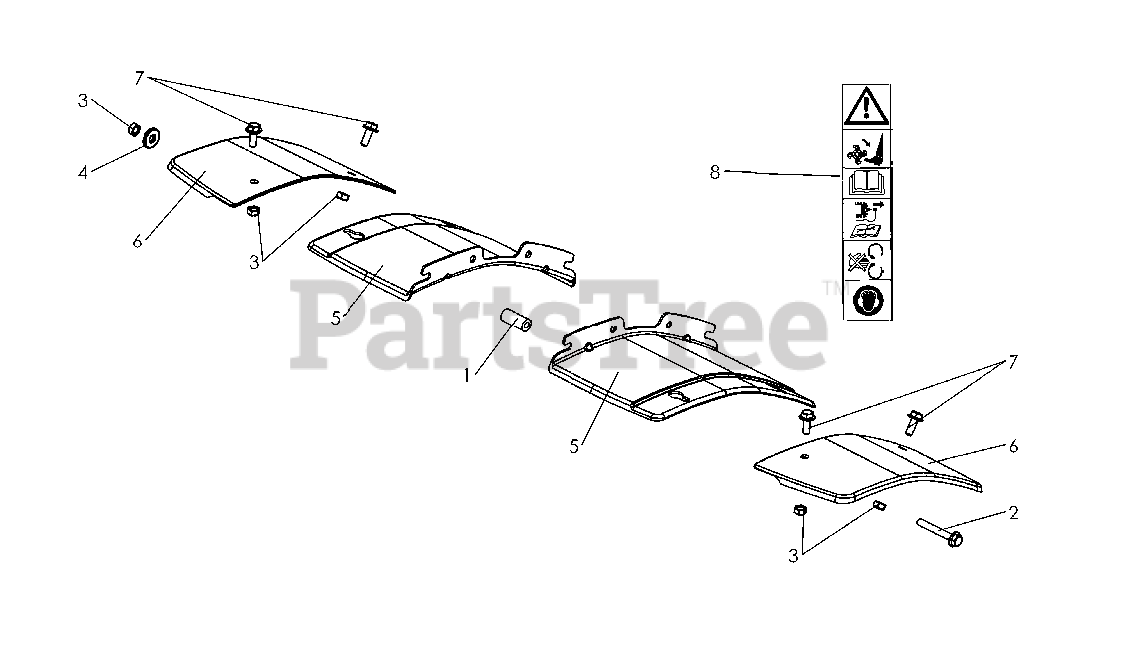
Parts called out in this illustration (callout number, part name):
3	Blocking nut M 6 Z
4	WASHER
7	SCREW
